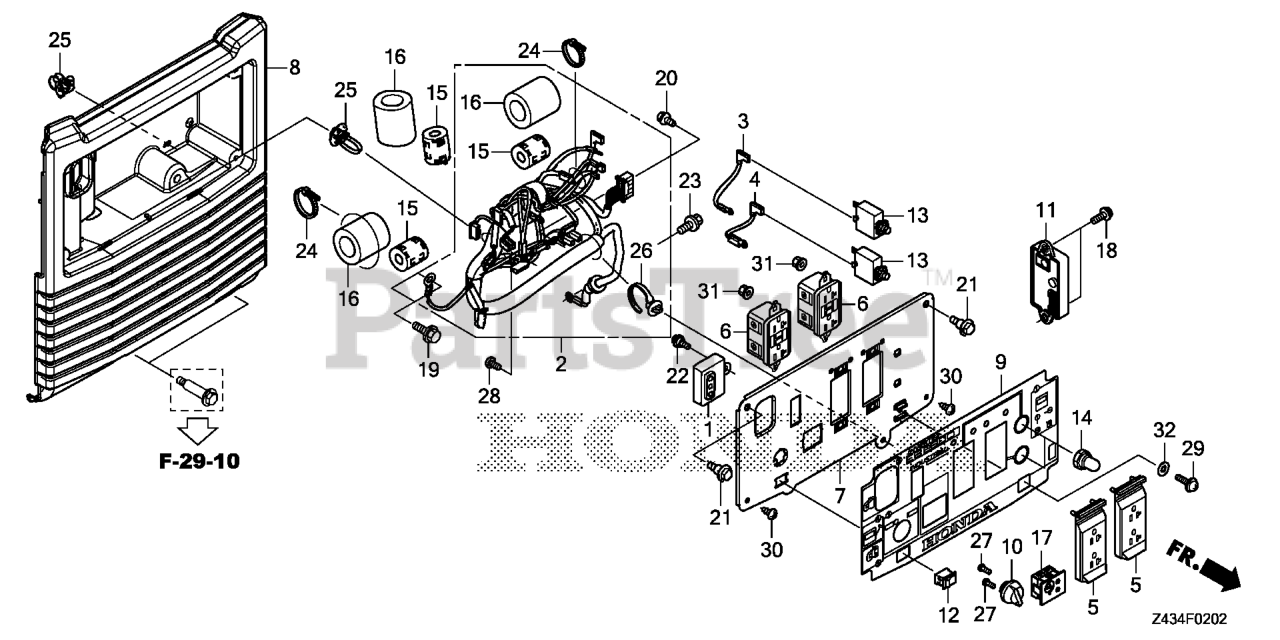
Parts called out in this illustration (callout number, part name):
1	IGNITION UNIT
2	WIRE HARNESS ASSY., CONTROL
3	WIRE, TERMINAL (200MM)
4	WIRE, TERMINAL (150MM)
5	COVER, RECEPTACLE (20A-125V)
6	RECEPTACLE (20A-125V) (GFCI)
7	PANEL, CONTROL
8	CASE, CONTROL PANEL *R280* (POWER RED)
9	MARK, CONTROL PANEL
10	SWITCH ASSY., ENGINE STOP
11	SENSING UNIT (CO)
12	SWITCH, AUTO THROTTLE
13	PROTECTOR, CIRCUIT (20A) (WHITE)
14	COVER, CIRCUIT PROTECTOR
15	FILTER, SUB NOISE (AC)
16	SUPPORTER, FILTER
17	LED ASSY., INDICATER
18	BOLT, FLANGE (5X14)
19	BOLT, FLANGE (6X14)
20	SCREW, TAPPING (5X12)
21	BOLT, CONTROL PANEL
22	SCREW, PAN (5X13)
23	BOLT, GROUND (6X12) (SN)
24	TIE, CABLE
25	CLIP, WIRE HARNESS
26	CLIP, HARNESS BAND (145MM) (BLACK)
27	SCREW, PAN (3X8)
28	SCREW, PAN (5X8)
29	SCREW, PAN (5X16)
30	SCREW, TAPPING (5X12)
31	NUT, FLANGE (4MM)
32	WASHER, PLAIN (5MM)
